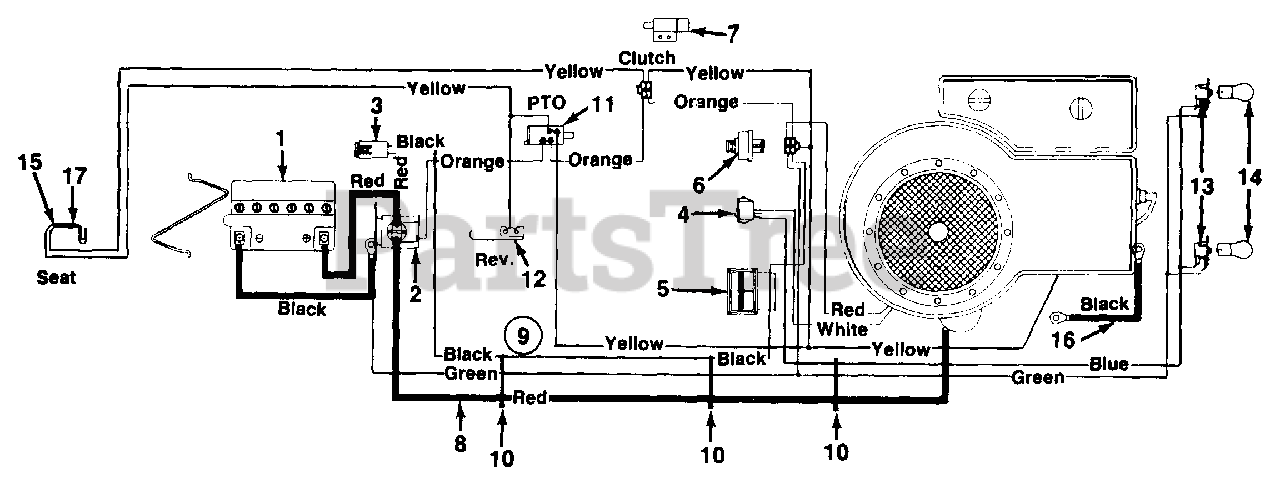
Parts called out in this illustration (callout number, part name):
1	Battery
2	Solenoid
3	Fuse 7.5 Amps
4	Light Switch
5	Ammeter
6	Ignition Switch
7	Safety Switch (Clutch)
8	Electric Wire 30" Lg. (B&S)
9	Wire Harness w/o Ammeter (B&S)
10	Cable Tie
11	Safety Switch (Deck)
12	Safety Switch (Reverse)
13	Socket
14	Bulb (Headlight)
15	Safety Switch (Seat)
16	Ground Wire 7.5" Lg.
17	Safety Switch (Seat)
